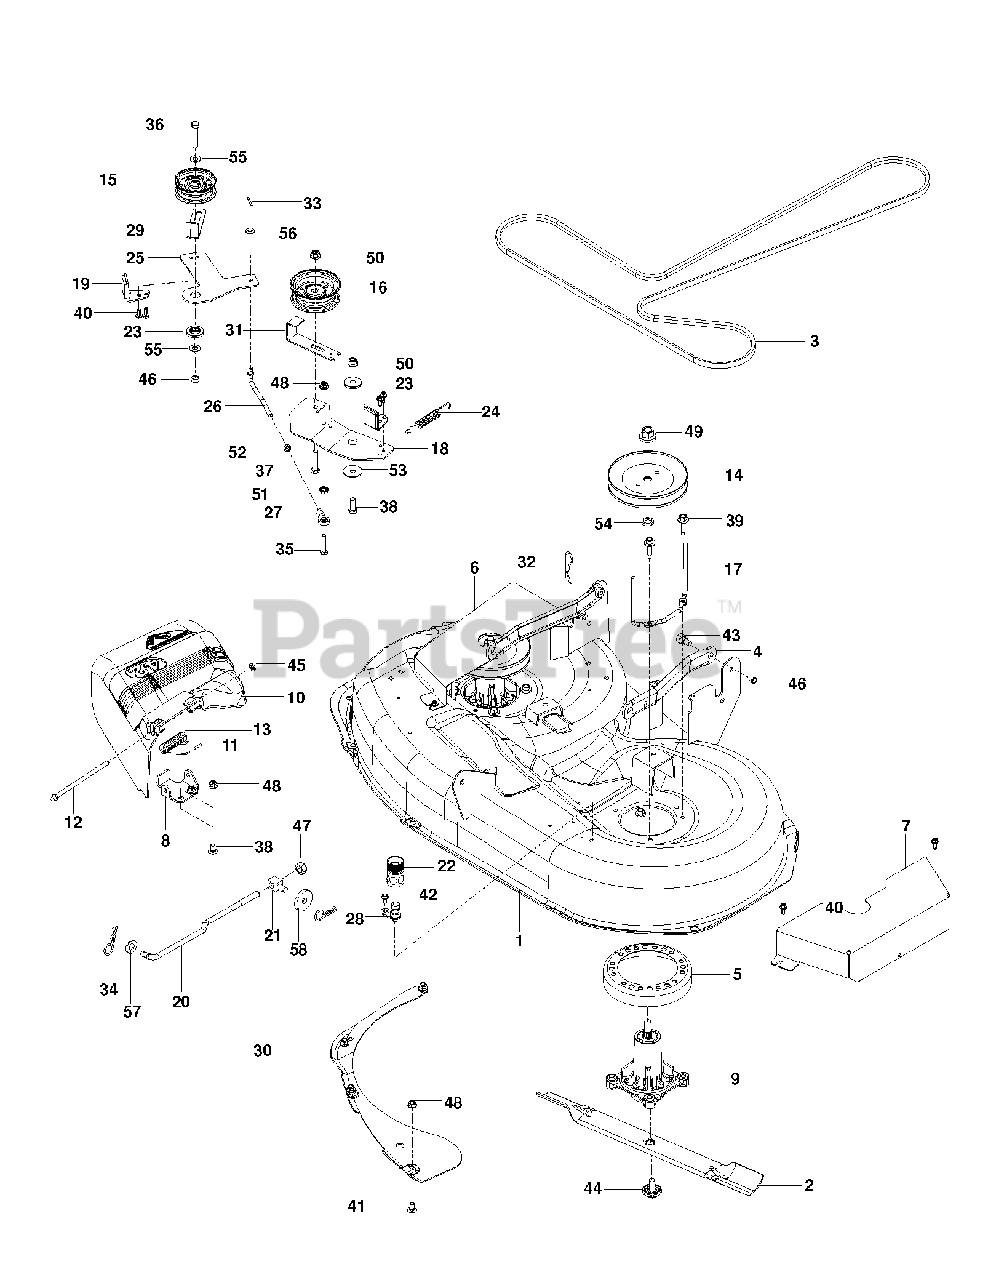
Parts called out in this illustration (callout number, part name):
1	DECK.SVC W/DECALS 42" HTC RZ
2	BLADE.42".MULCH
3	BELT, EL118
4	ARM.SUSPENSION.MOWER
5	STRIPPER-ROUND-UNIVERSAL
6	GUARD.RIGHT.BELT.42"BLACK
7	GUARD.LEFT.BELT.42" BLACK
8	BRKT.DEFLECTOR.38"2005+
9	RB MANDREL.ASM.SUB-NON.GR
10	DEFLECTOR 42
11	CAP-SLEEVE
12	ROD, HINGE
13	SPRING, TORSION DEFLECTOR
14	PULLEY.MANDREL.5.438.P
15	IDLER PULLEY
16	PULLEY.IDLER.FLAT
17	BELT KEEPER.MANDREL.38"COATED
18	ARM.IDLER.BLACK
19	ARM, LH BRAKE
20	LINK LIFT SUSP. FRONT MOWER
22	COUPLING.QUICK CONNECT
23	SPACER.RETAINER
24	SPRING RETURN
25	ARM.BRAKE.42.BLACK
26	LINKAGE, DECK BRAKE
27	BALL JOINT, RIGHT HANDED
28	PORT.WASHOUT
29	GUIDE, BELT
30	BAFFLE VORTEX 42
31	KEEPER, BELT
32	SPRING.RETAINER.YELLOW.ZINC
33	RP_COTTER PIN 1/8 X 3/4
34	HAIRPIN #4
35	CAPSCREW 5/16 X 1/1/2 HEX HEAD
36	HCS 3/8C X 2
37	HCS 3/8-16 X 1 3/4 GR5
38	HCS 3/8-16X1.GRD.5.ZD
39	WASHER HEAD SCREW
40	SCREW- 1/4-20 X 5/8
41	CARRIAGE BOLT 5/16C X 5/8"
42	SCREW 3/8C X 3/4 HEX CAP
43	SB 3/8-16 X 3/8 SKT HD ZD
44	BOLT.WASHER.ASM.7/16-2
45	RT HEADLIGHT REFLECTOR
46	NUT HEX 3/8-16 NYLON, THIN
47	NUT, 7/16-20 HEX NYLOC ZC
48	5/16-18 NYLOC FLANGE NUT
49	LOCKNUT - 9/16
50	NUT 3/8-16 HEX FLG NYLOC ZD
51	NUT 5/16C WHIZ
52	NUT 5/16C HEX
53	WASHER, FRICTION
54	WASHER-SPACER
55	WASHER 3/8 SAE FLAT
56	FLAT WASHER 5/16 SAE
57	WASHER 1/2" FLAT
58	SPINDLE WASHER
